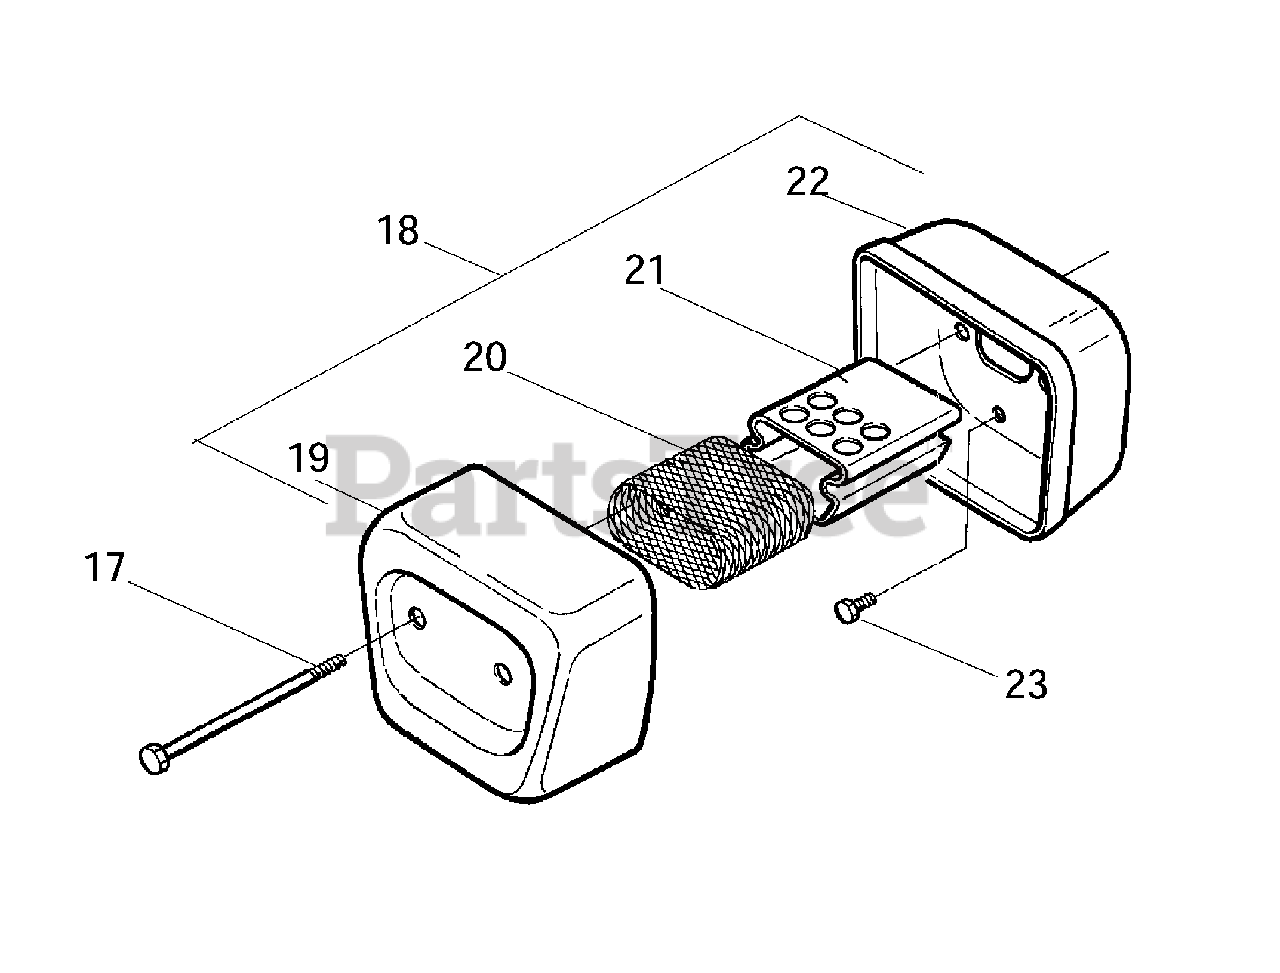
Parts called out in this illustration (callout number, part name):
18	Muffler Kit
19	Muffler Cover
20	Spark Arrestor Screen
21	Muffler Diffuser
22	Muffler Body
23	Muffler Bolt
